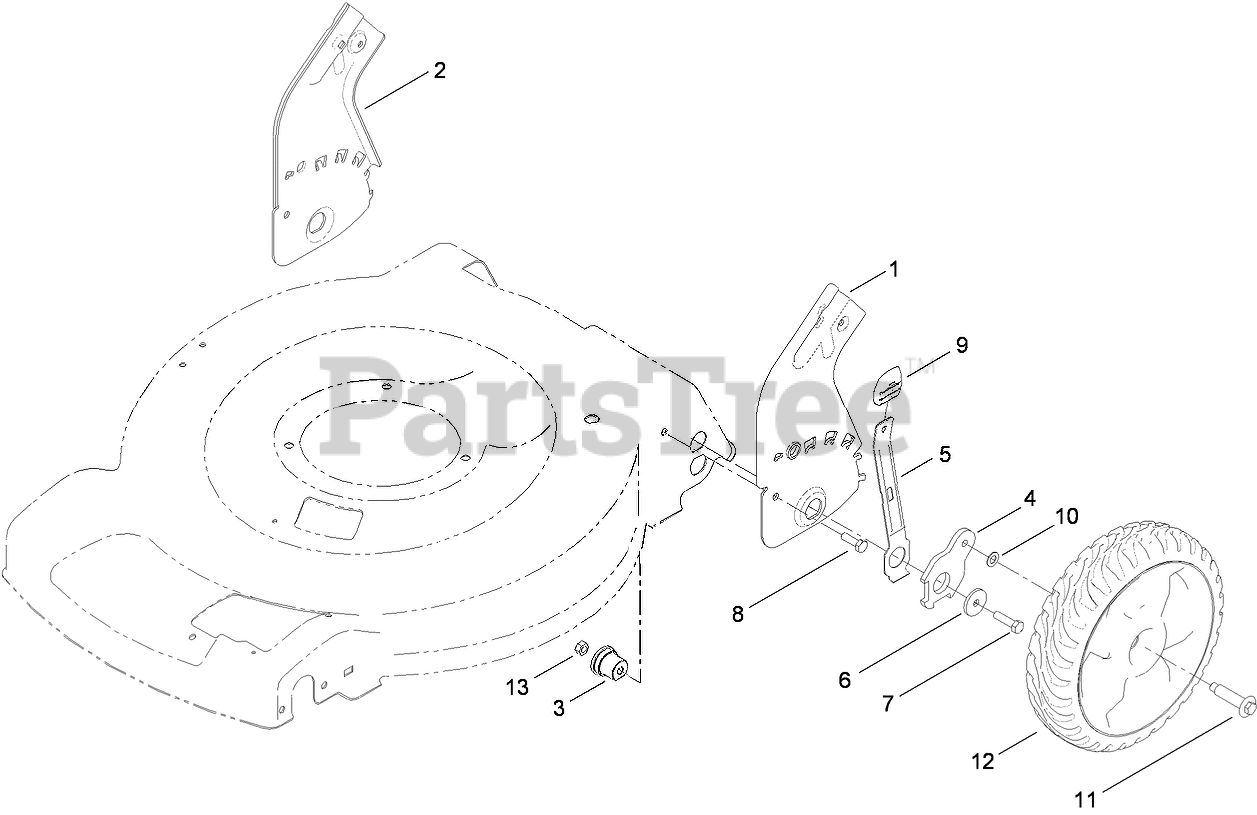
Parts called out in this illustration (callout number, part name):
1	PLATE-HOC, REAR (LH)
2	PLATE-HOC, REAR (RH)
3	BUSHING-MOUNT, HOC
4	ARM-PIVOT, REAR
5	ARM-SPRING, REAR
6	Washer-Flat
7	SCREW-HH
8	SCREW-HH
9	Knob-Lever, HOC
10	WASHER
11	BOLT-SHOULDER
12	11 INCH WHEEL ASM
13	NUT-LOCK, NI
